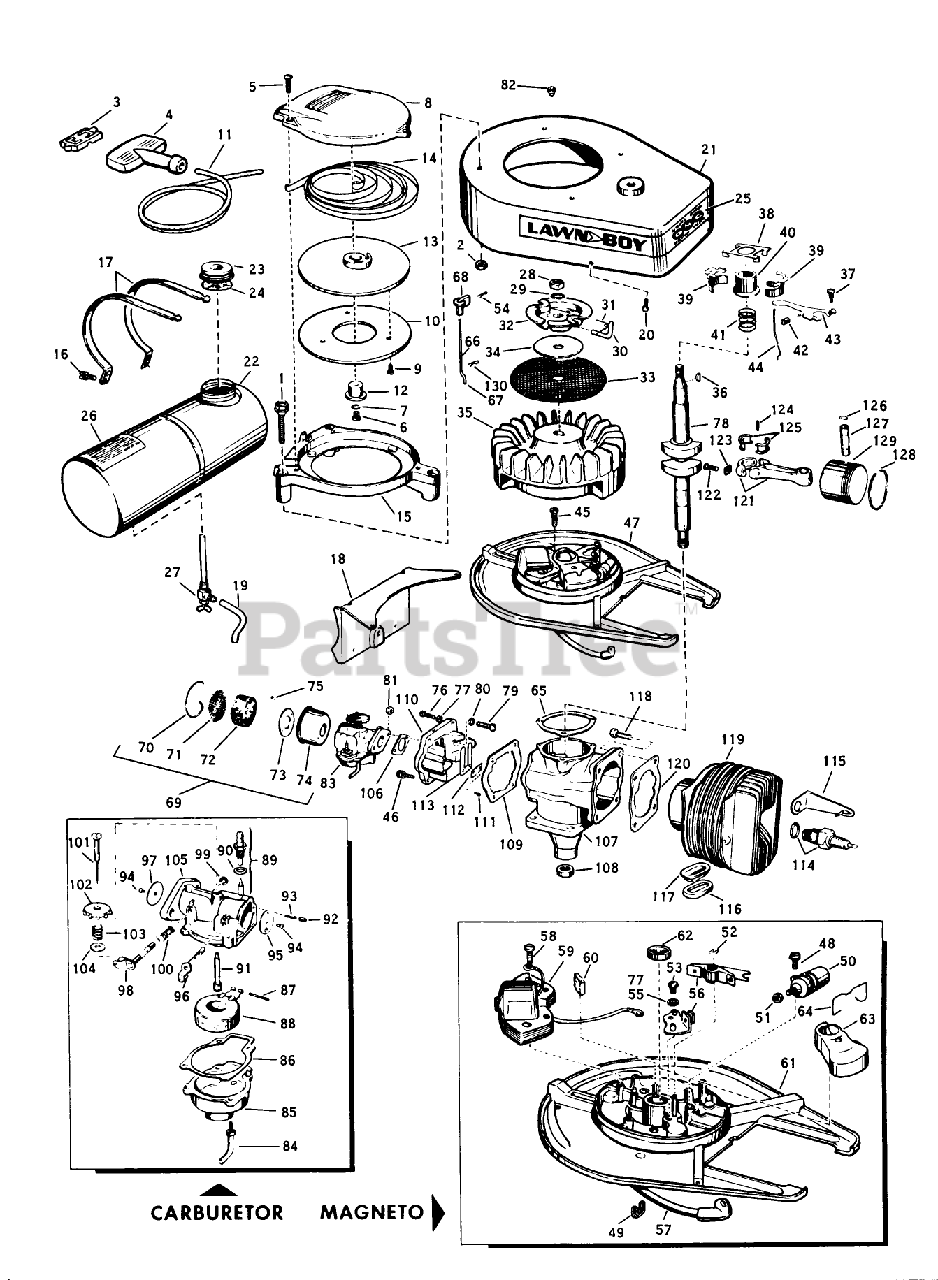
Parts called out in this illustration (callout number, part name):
10	Plate-Pulley
14	RECOIL SPRING
20	SCREW S
25	Decal-"LAWN-BOY"
27	VALVE&SCREEN SM
30	PIN - STARTER
40	COLLAR S
42	WEAR BLOCK S
43	GOVERNER LEVER AY
44	GOVERNOR ROD S
46	SCREW S
54	Cotter Pin
56	BREAKER AY. S
65	GASKET S
68	KNOB, CHOKE BAR
72	ELEMENT
73	BACK-UP PLATE
76	SCREW S
81	STOP NUT
94	Screw-Choke Disc
100	SPRING
101	NEEDLE AY. S
103	Spring-Ndl. Adj.
106	GASKET S
112	PLATE-BACKUP, REED
114	Spark Plug
116	GASKET S
120	GASKET S
125	LINER ASM
130	Cotter Pin
